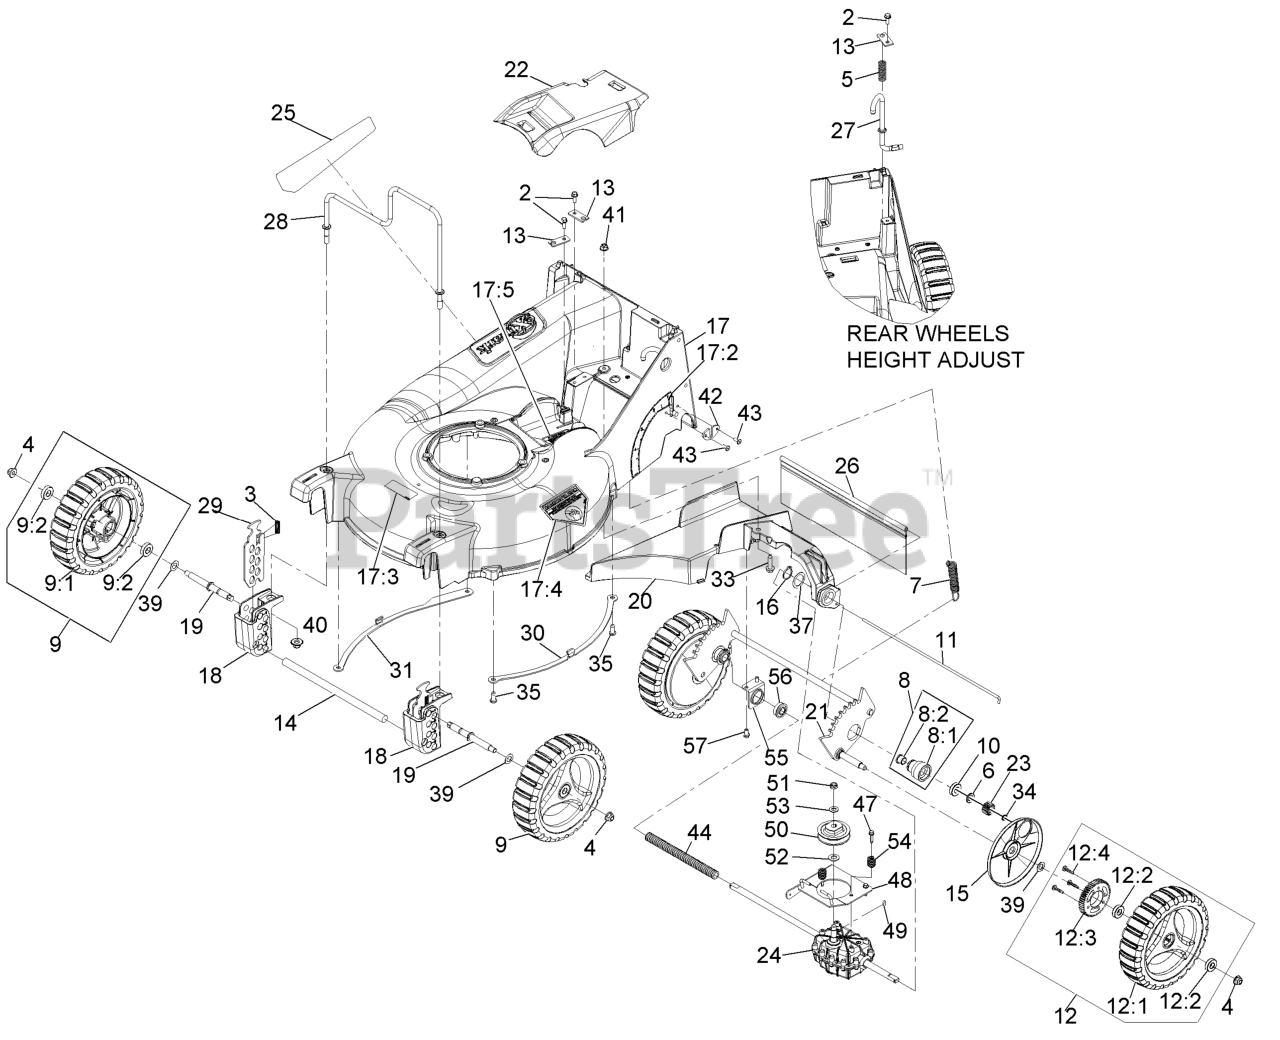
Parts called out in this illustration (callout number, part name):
2	SCREW-HWH
3	SPRING-COMPRESSION
4	NUT-HF, NI
5	SPRING-COMPRESSION
6	SPACER-BUSHING
7	SPRING-EXTENSION
8	HOUSING ASM
8:1	HOUSING-BEARING
8:2	BEARING-FLANGE
9:2	BEARING-BALL
10	BEARING-BALL
11	ROD,SHIELD
12:2	BEARING-BALL
12:4	SCREW-DRIVE
13	BRACKET,MOUNT
14	ROD,BUMPER
15	COVER,GEAR
16	RING-RETAINING
17	DECK W/DECALS
17:2	DECAL-HEIGHT OF CUT
17:3	DECAL-BLADE
17:4	DECAL-DANGER
17:5	DECAL-COVER MISSING
18	BLOCK,FRONT QUADRANT
19	AXLE-WHEEL
20	BRACKET-TRANSMISSION AND
21	WLD,REAR AXLE P21
22	COVER,BELT
24	TRANSMISSION-HD, 4.5/1
25	DECAL-COMM 21 X-SERIES
26	SHIELD-TRAILING P21
27	ROD-HEIGHT ADJ P21
28	GUARD,ENGINE
29	PLATE, FRONT HEIGHT
33	SCREW-HWHTF
34	RING-RETAINING
35	SCREW-BHTF
39	WASHER-PLAIN
40	Nut-Nyloc 3/8-16 Flg
41	NUT-HF, NI
42	PLATE,WEAR
43	RIVET-BLIND
44	COVER-SHAFT-DRIVE
47	SCREW-SPECIAL
48	TRANSMISSION PLATE ASM
49	KEY-WOODRUFF
51	NUT-HEX
52	WASHER-THRUST
53	WASHER-FLAT
54	SPRING,COMPRESSION
56	BEARING-BALL
57	SCREW-HWH
